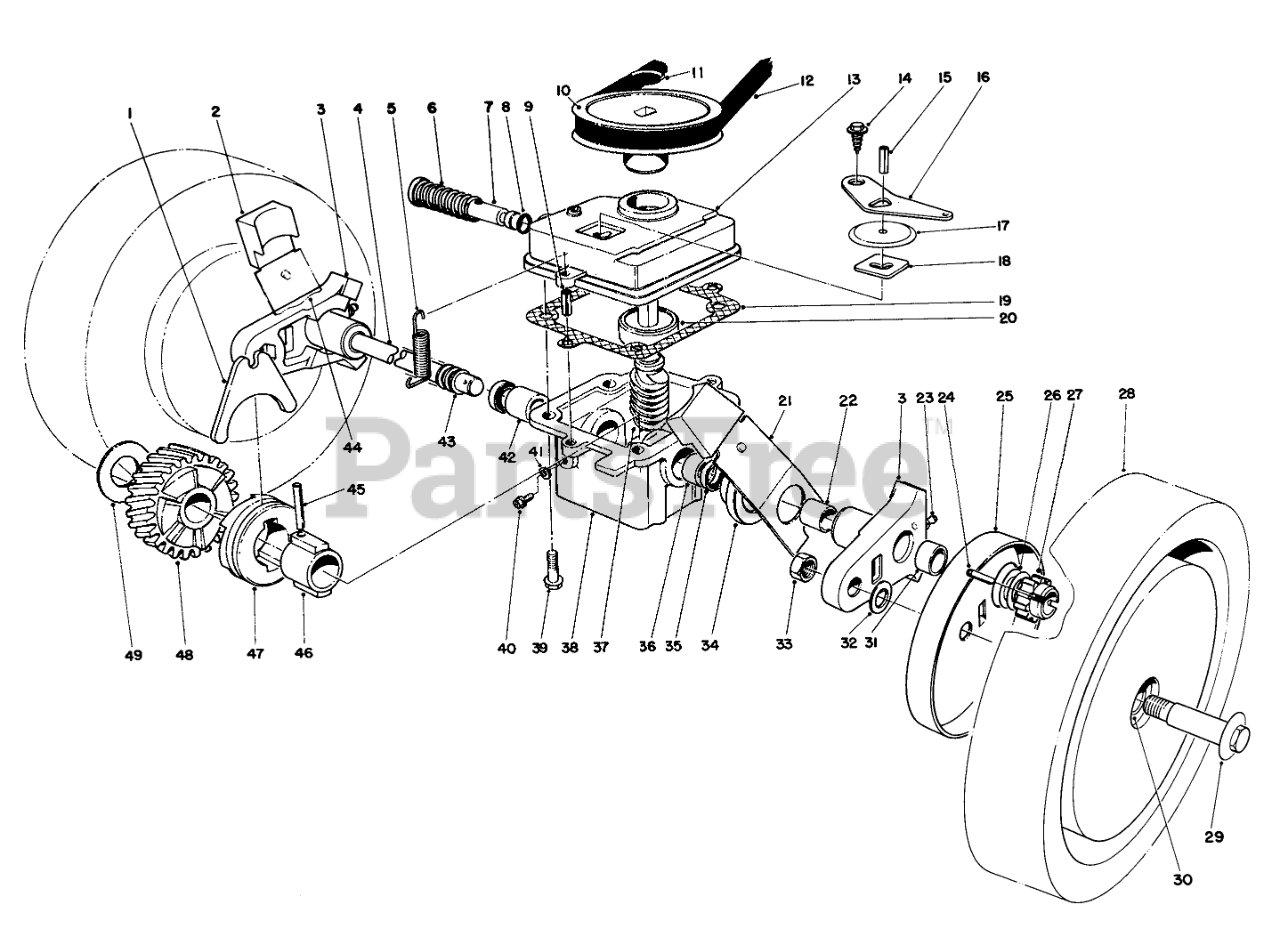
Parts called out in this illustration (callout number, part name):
1	SHIFTER FORK
2	KNOB-ARM
3	Pivot Arm (Incl. Ref. #22, 23&31)
4	DRIVE SHAFT (SERVCE)
5	TENSION SPRING
6	SPRING
7	SHIFTER ROD
8	O-RING
9	3/16 X 1/2 ROLL PIN
10	PULLEY
11	PUSH-ON 93-3236
12	V-Belt
13	Case-Upper
14	Screw
15	PIN-ROLL
16	SHIFTER ARM
17	TRANS DUST COVER
18	LATCH PLATE
19	GASKET
20	BEARING
21	SPRING ARM ASM SP LH
22	BUSHING
23	FITTING-GREASE
24	Pin
25	WHEEL COVER
26	THRUST WASHER
27	PINION GEAR 14T
28	Wheel, Tire & Gear Assembly (Incl. Ref. #30)
29	WHEEL BOLT
30	BUSHING
31	BUSHING
32	WASHER
33	NUT-LOCK
34	CAP-END
35	SEAL-OIL
36	BUSHING
37	Worm Shaft & Gear (Incl. Ref. #48)
38	Gear Case (Incl. Ref. #35-36 & 42)
39	Screw
40	NYLON SCREW
41	FILL PLUG GASKET
42	BUSHING
43	COVER-SHAFT, DRIVE
44	SPRING ARM ASM SP RH
45	COIL PIN
46	SLEEVE
47	CLUTCH JAW
48	Helical Gear
49	THRUST WASHER
